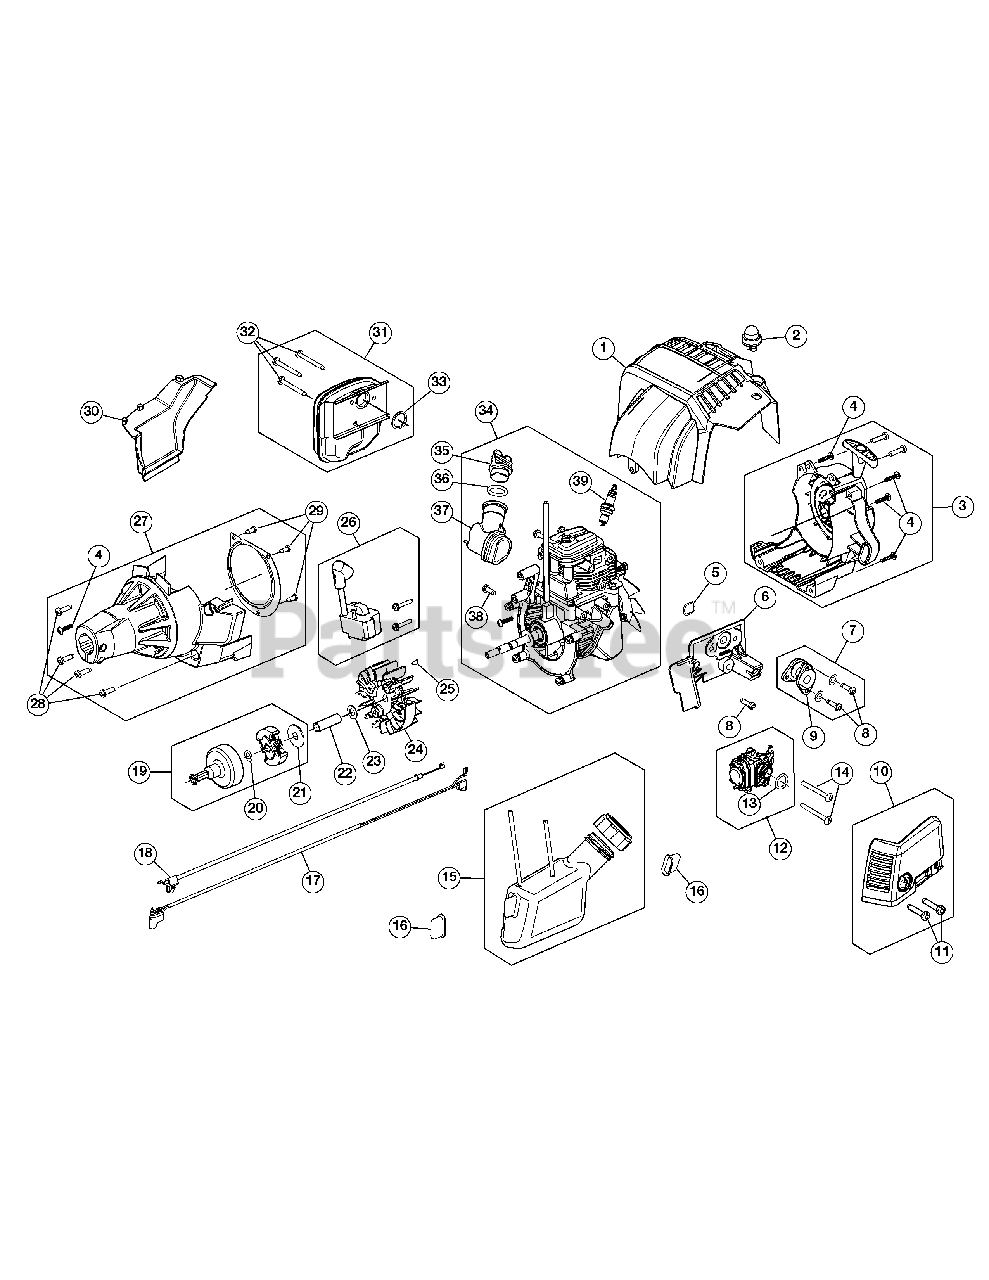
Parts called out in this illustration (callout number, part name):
1	Top Housing
2	Air Purge Primer
3	Starter Housing Assembly (Incl. 4)
5	O-Ring
6	Intake Port
7	Boot Assembly (Incl. 8 & 9)
8	Screw
10	Air Cleaner Assembly
12	Carburetor Assembly (Incl. 13)
15	Fuel Tank Assembly
16	Fuel Tank Pad
17	Lead Wire
18	Throttle Cable
19	Clutch Assembly (Incl. 20 & 21)
20	Thrust Washer
21	Clutch Washer
22	Spacer
23	Washer
24	Flywheel
26	Module Assembly
27	Clutch Cover Assembly (Incl. 28 & 29)
28	Screw
29	Screw
30	Rear Engine Cover
31	Muffler Assembly (Incl. 32 & 33)
33	Muffler Gasket
34	Shortblock Assembly (Incl. 35 - 39)
35	Oil Fill Plug
36	O-Ring
37	Oil Fill Tube Assembly
38	Screw
39	Spark Plug
